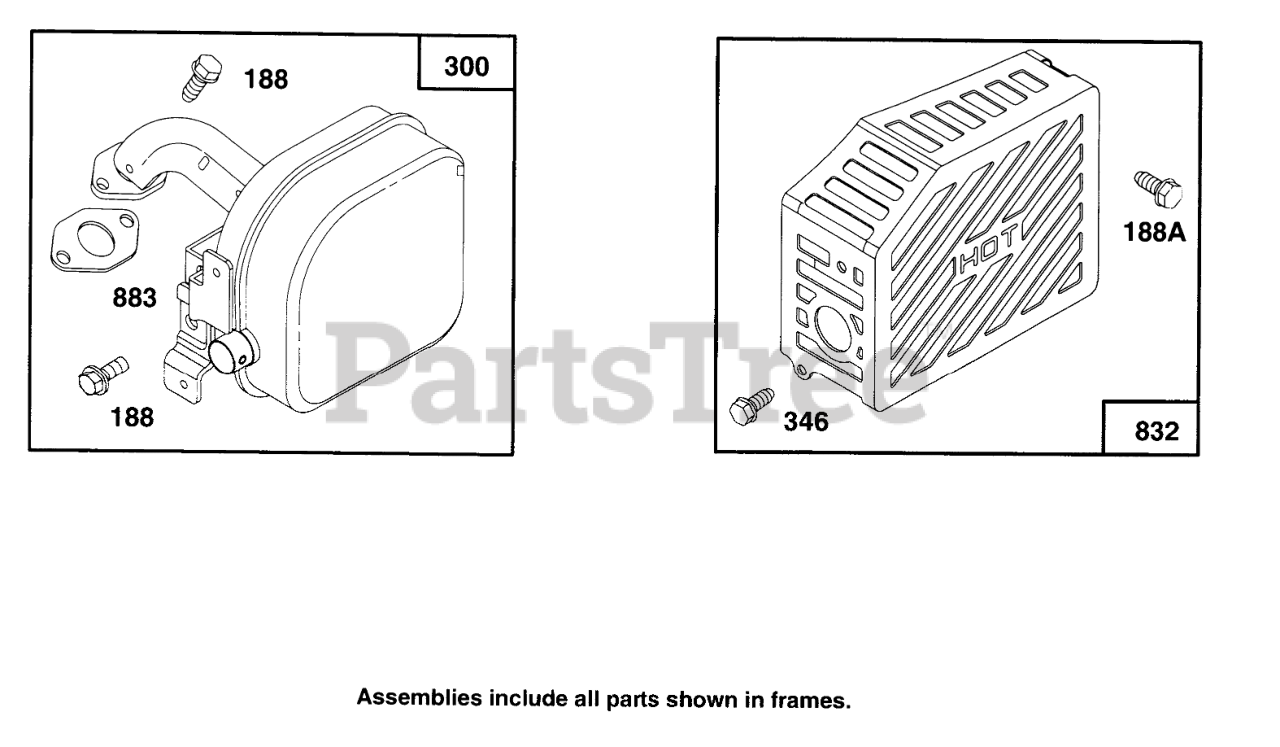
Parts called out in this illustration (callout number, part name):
188	Screw-Cap
188A	SCREW - HEX HEAD
300	MUFFLER - EXHAUST
346	Screw-Hex
832	Guard-Muffler
883	EXHAUST GASKET
